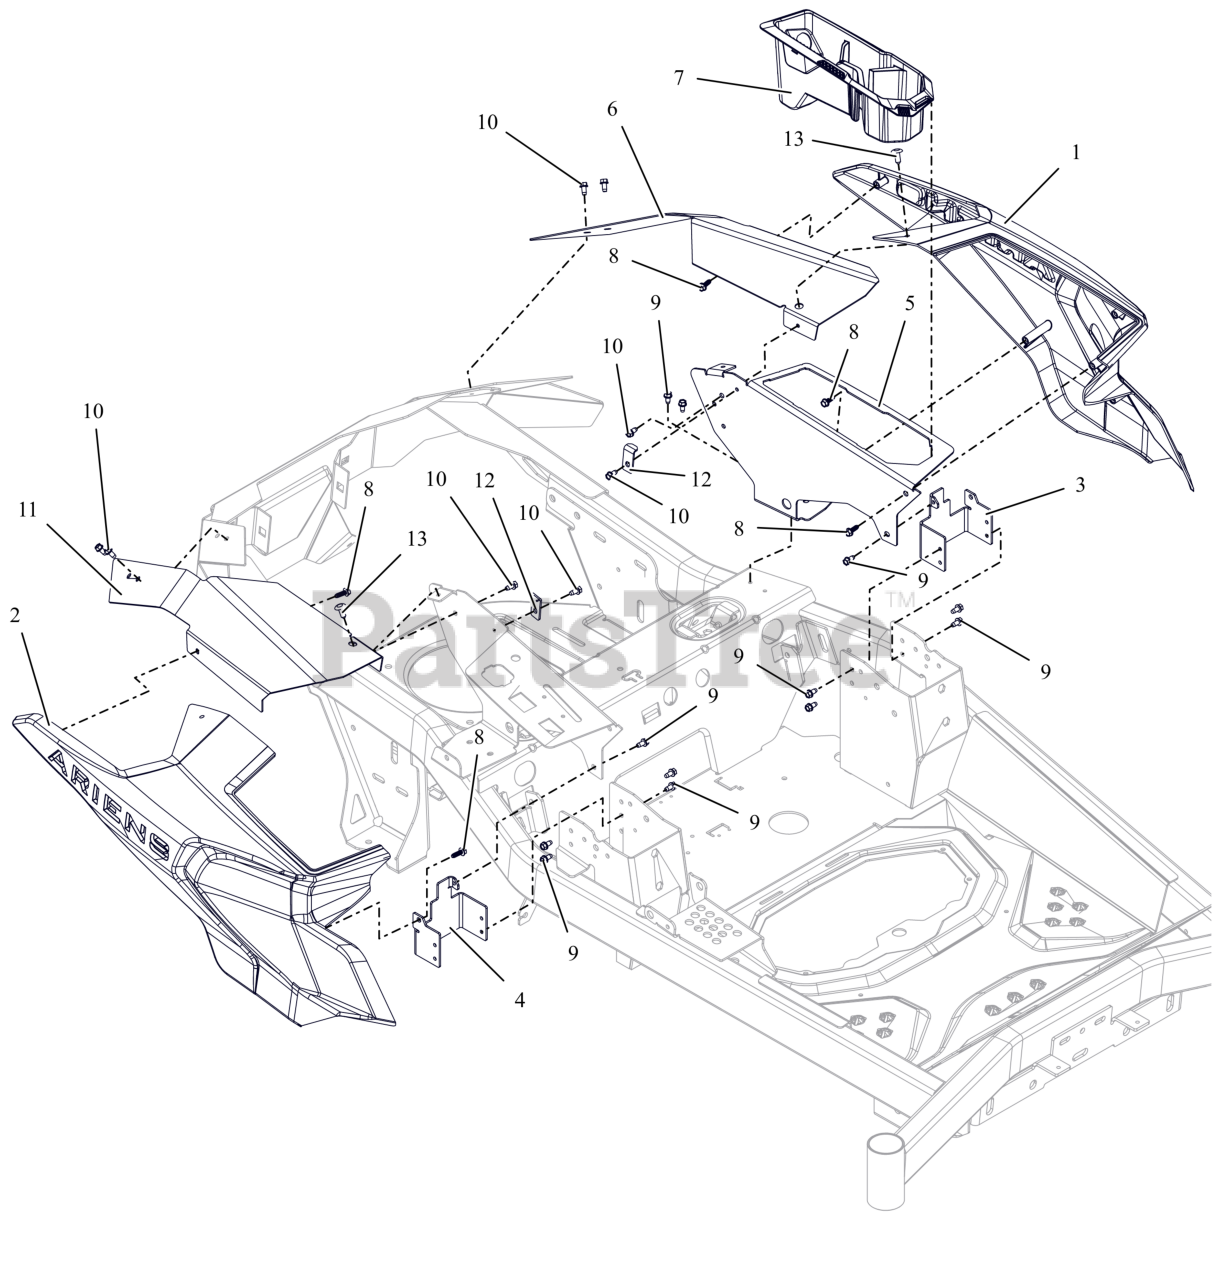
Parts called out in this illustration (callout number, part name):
1	KIT,LH ARIENS FENDER W/ DECAL
2	FENDER-RH-ARIENS
3	BRKT-FRONT FENDER MOUNT-A-RH
4	BRKT-FRONT FENDER MOUNT-A-LH
5	PANEL, CONTROL -LH-ARIENS (BLACK)
6	BRKT, REAR FENDER MOUNT-A-LH (BLACK)
7	HOLDER- CUP - IKON
8	SCR, PLASTITE .25-10X.75 ZCC
9	SCR-TAP .25-20X.50 HWH ZCC
10	SCR-TAP .25X.50 HWH ZB500
11	BRKT, REAR FENDER MOUNT-A-LH (BLACK)
12	PLATE, FENDER HOLDDOWN (BLACK)
13	XMAS TREE FASTNER-BLACK
